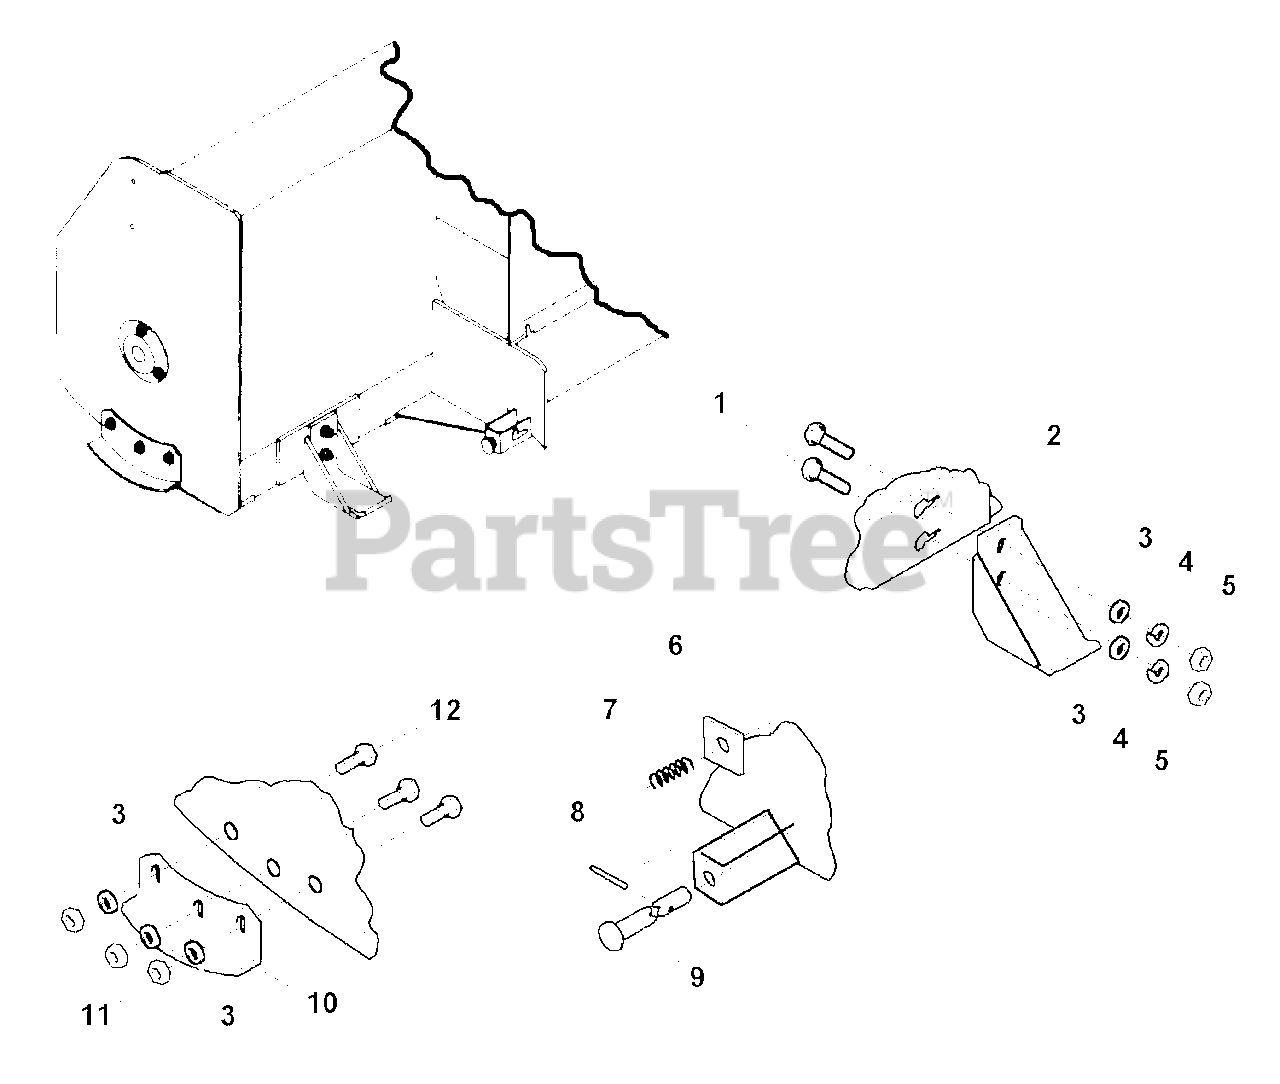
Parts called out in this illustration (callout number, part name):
1	CARRIAGE BOLT, 5/16-18 x 1-1/4
2	SKID SHOE, Snowthrower
3	WASHER, 5/16
4	LOCKWASHER, 5/16
5	NUT, Hex, 5/16-18
6	WASHER, Shot Pin
7	SPRING, Shot Pin
8	PIN, Roll, 1/4 x 1-1/2
11	LOCKNUT, Hex, 5/16-18
12	CAPSCREW, Hex Head, 5/16-18 X 3/4
